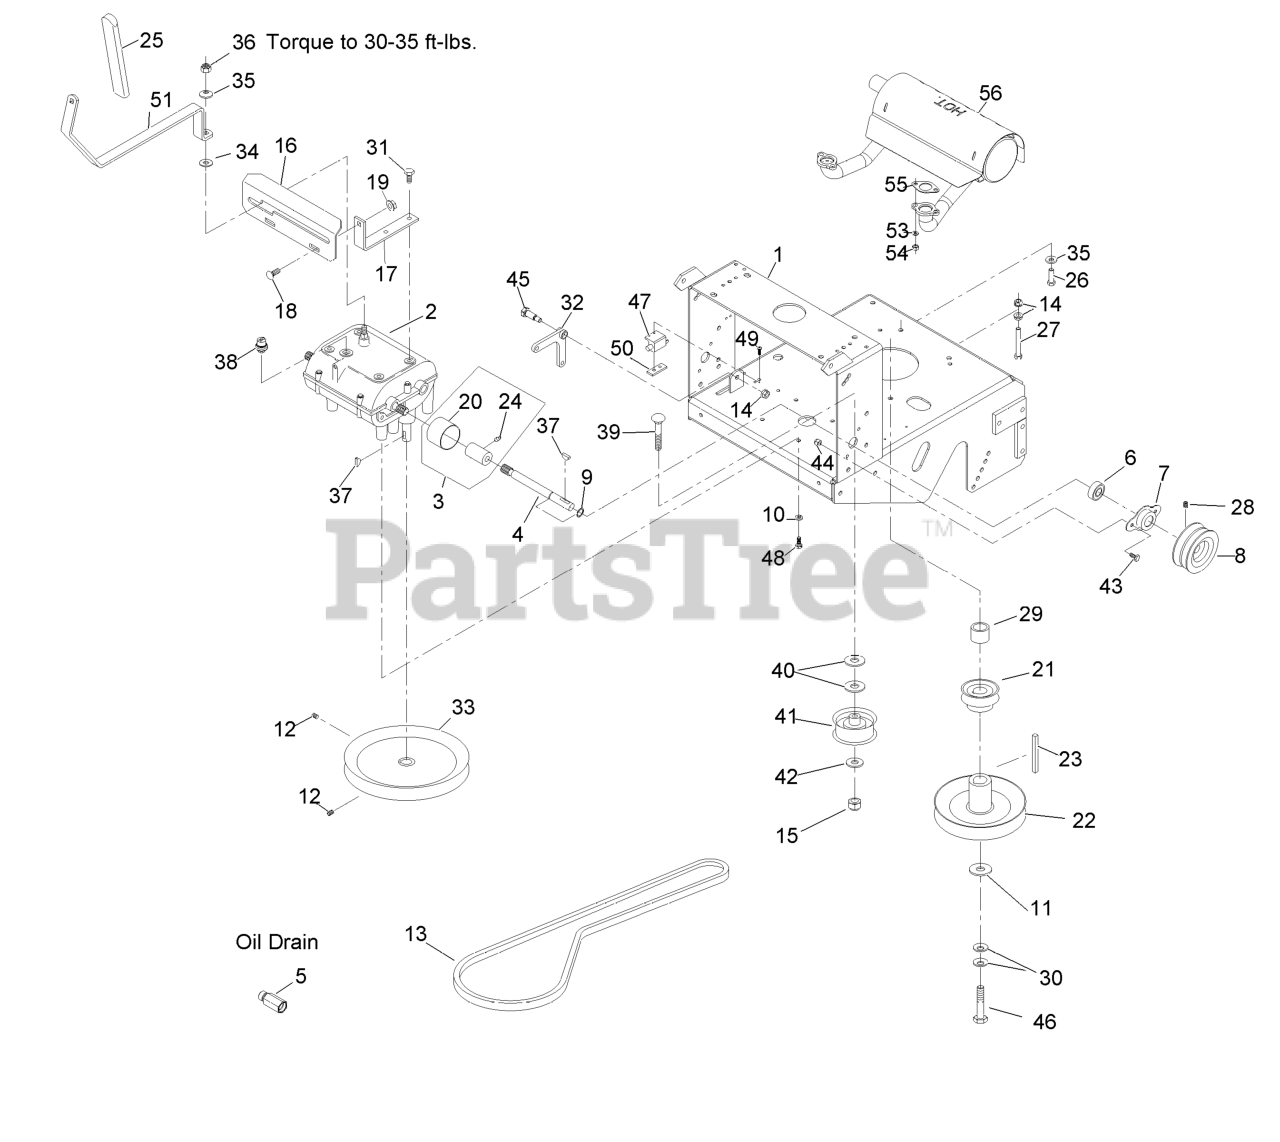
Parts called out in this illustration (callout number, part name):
3	ASM,COUPLER/ZERK
4	SHAFT-TRANSMISSION
5	ADAPTER
6	BEARING-SHAFT
7	FLANGE-OUTPUT
8	SHEAVE-TRANSMISSION
9	RING-RETAINING
10	WASHER-LOCK
12	SCREW-HSH
13	BELT,TRANS DRIVE
14	NUT-HHF, WHIZ
15	NUT-LOCK, NI
16	PLATE,SHIFTER W/DECAL
17	BRACKET-PLATE, SHIFT
18	BOLT-CARR
20	GUARD-COUPLER
21	SHEAVE-TRANSMISSION
24	FITTING-GREASE
25	GRIP,FOAM
26	SCREW-HH
27	SCREW-HH
28	SETSCREW
29	SPACER-CLUTCH
30	WASHER-SPRING
31	SCREW-HWH, THREAD CUT
32	BELLCRANK
33	SHEAVE-TRANSMISSION
35	WASHER-BELLEVILLE
36	NUT-LOCK
37	KEY-WOODRUFF
38	SWITCH-START, NEUTRAL
39	SCREW-HH
40	WASHER-FLAT
42	WASHER-FLAT
43	SCREW-HH
44	NUT-LOCK, NI
45	BOLT-SHOULDER
46	SCREW-HH
47	SWITCH-OPEN, NORMALLY
48	SCREW-HH
49	SCREW-PPH
50	PLATE-TAPPED
51	ASM,SHIFT LEVER
53	WASHER-LOCK
55	GASKET-EXHAUST
56	MUFFLER-HORIZONTAL, OFFSE
